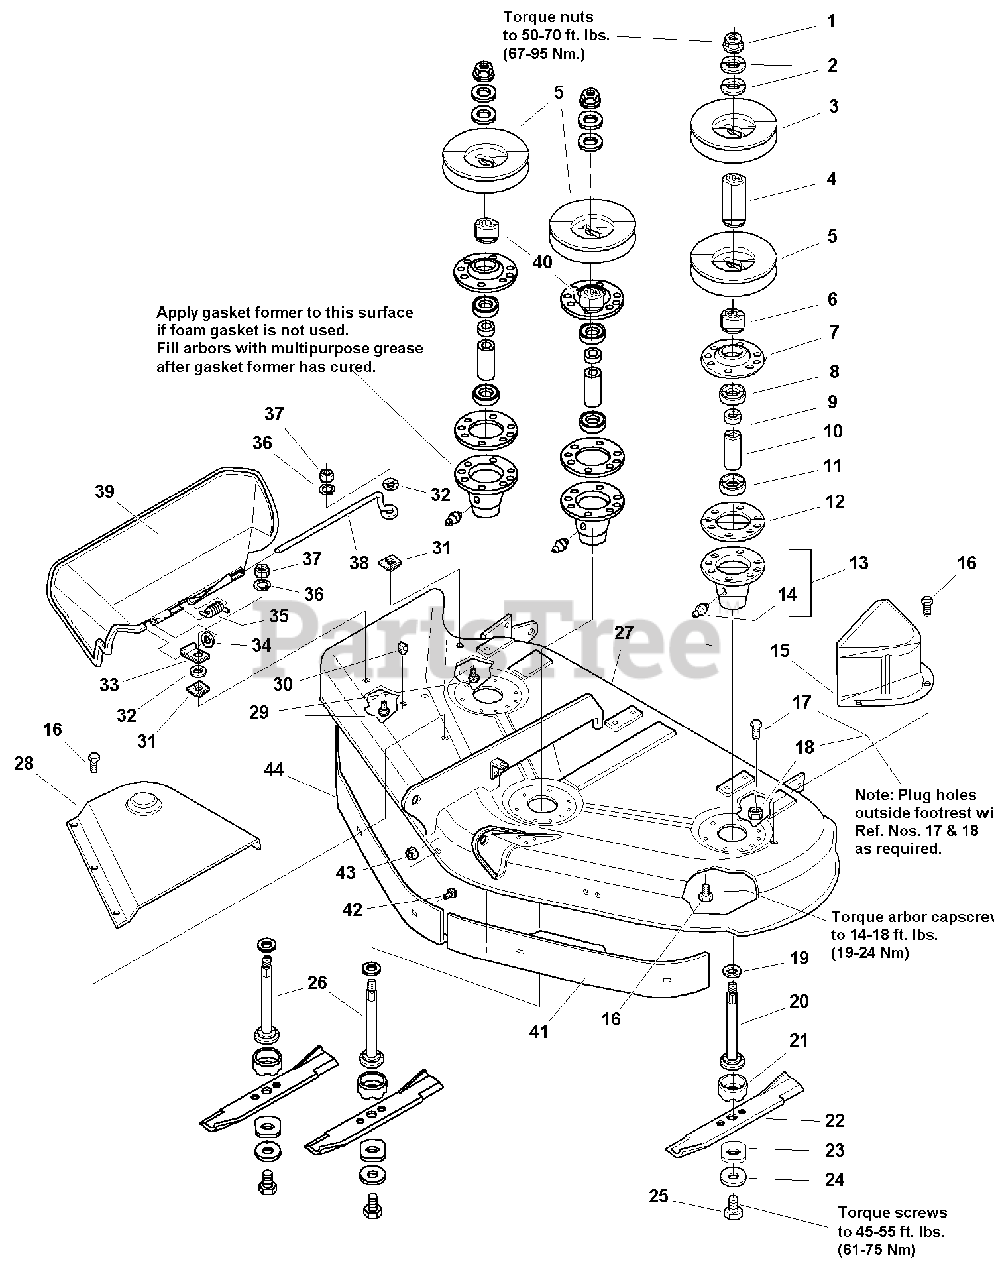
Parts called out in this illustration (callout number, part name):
1	NUT, Hex Flange, 9/16-18
2	WASHER, Bellville, 9/16
3	PULLEY
4	HUB, Double Pulley
5	PULLEY
6	HUB, Double Pulley
7	COVER, Arbor Housing
8	BEARING, Ball, 3/4 x 1-3/4 x 5/8
9	SPACER, 21/32 x 3/4 x 5/8
10	SPACER, 11/16 x 5/32 x 2-11/16
11	BEARING, Ball, 11/16 x 1-9/16 x 15/32
12	GASKET, Foam
13	ARBOR HOUSING ASSEMBLY, (Includes Ref. No. 14)
14	FITTING, Grease
15	COVER, Arbor
16	CAPSCREW, Hex Head Taptite, 5/16-18 x 3/4
17	CAPSCREW, Hex Washer Head, 5/16-18 x 1/2, Black
18	NUT, Hex Flange, 5/16,
19	WASHER, Bellevilled, 9/16, Black
20	SHAFT, Arbor (LH)
21	SHIELD, Grass, Lower
22	BLADE, Mower, 16-1/8 (for 44" Decks)
23	WASHER, Hex, 11/16 x 2
24	WASHER, Spring 15/32, Black
25	CAPSCREW, Hex Head, 7/16-14 x 1
26	SHAFT, Arbor (Center & RH)
27	MOWER HOUSING ASSEMBLY, 44" Mower (Orange)
27	MOWER HOUSING ASSEMBLY, 44" Mower (Red)
28	COVER, Arbor
29	CARRIAGE BOLT, 1/4-20 x 7/8
30	PLUG, Hole
31	NUT, Push
32	WASHER, 1/4, Black
33	CLAMP
34	WASHER, 5/16, Black
35	SPRING
36	WASHER, Lock, 1/4
37	NUT, Hex, 1/4-20
38	ROD, Deflector, Front
39	DEFLECTOR, Plastic
40	HUB, Pulley, Center & RH
41	BAFFLE, Anti-Blowout, LH (CE Only)
42	CARRIAGE BOLT, 5/16-18 x 3/4, Black (CE Only)
43	NUT, Hex Flange Whiz Lock, 5/16-18, Black (CE Only)
44	BAFFLE, Anti-Blowout, RH (CE Only)
